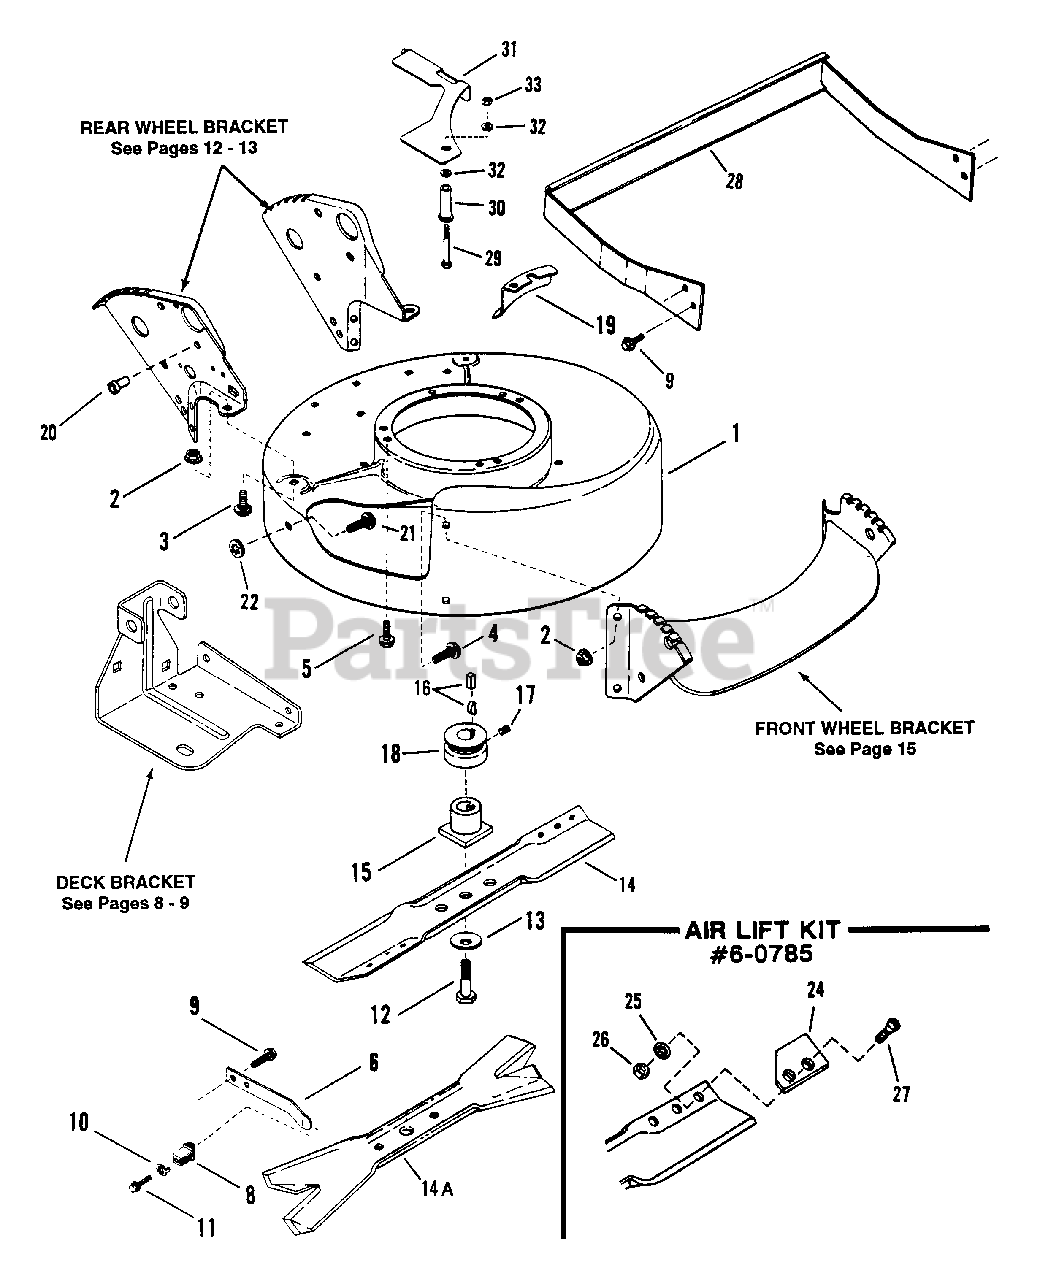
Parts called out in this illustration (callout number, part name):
1	DECK, Mower
2	NUT, 5/16-18 Hex Flange Lock
3	BOLT, 5/16-18 x 1/2" Short Neck Carriage
4	BOLT, 5/16-18 x 1-1/8" Short Neck Carriage
5	SCREW, 3/8-18 x 1" Self-Tapping (Engine Mounting)
6	SPRING, Wheel Bracket Type Interlock
8	INSULATOR, Interlock
9	SCREW, 1/4-20 x 1/2" Self-Tapping
10	WASHER, #8 Tab Internal Tooth Lock
11	SCREW, #8-18 x 3/4" Hex Machine
12	SCREW, 3/8-24 x 2" Hex Head Cap (Gr. 5)
13	WASHER, Cone
14	BLADE, Cutter (20.75")
14A	BLADE, Cutter (20.75")(Quad Edge)
15	HUB, Blade Drive 25mm (Briggs & Robin)
16	KEY, 3/16 x 5/8" Woodruff (Briggs)
17	SCREW, 5/16-18 x 5/16" Hex Socket Set
18	PULLEY, Engine (Briggs)
19	SHIELD, Belt Opening Cover
20	BUSHING, Interlock Wire
21	BOLT, 5/16-18 x 3/4" Short Neck Carriage
22	RETAINER, 5/16 Bolt
24	LIFT, Air
25	WASHER, 5/16 Internal Tooth Lock
26	NUT, 5/16-24 Hex
27	SCREW, 5/16-24 x 21/32" Machine
28	STRUCTURE, Fender
29	BOLT, 5/16-18 x 2-1/4" Hex Flange Lock
30	BUSHING
31	COVER, Belt
32	WASHER, 5/16 Split Lock
33	NUT, 5/16-18 Hex
